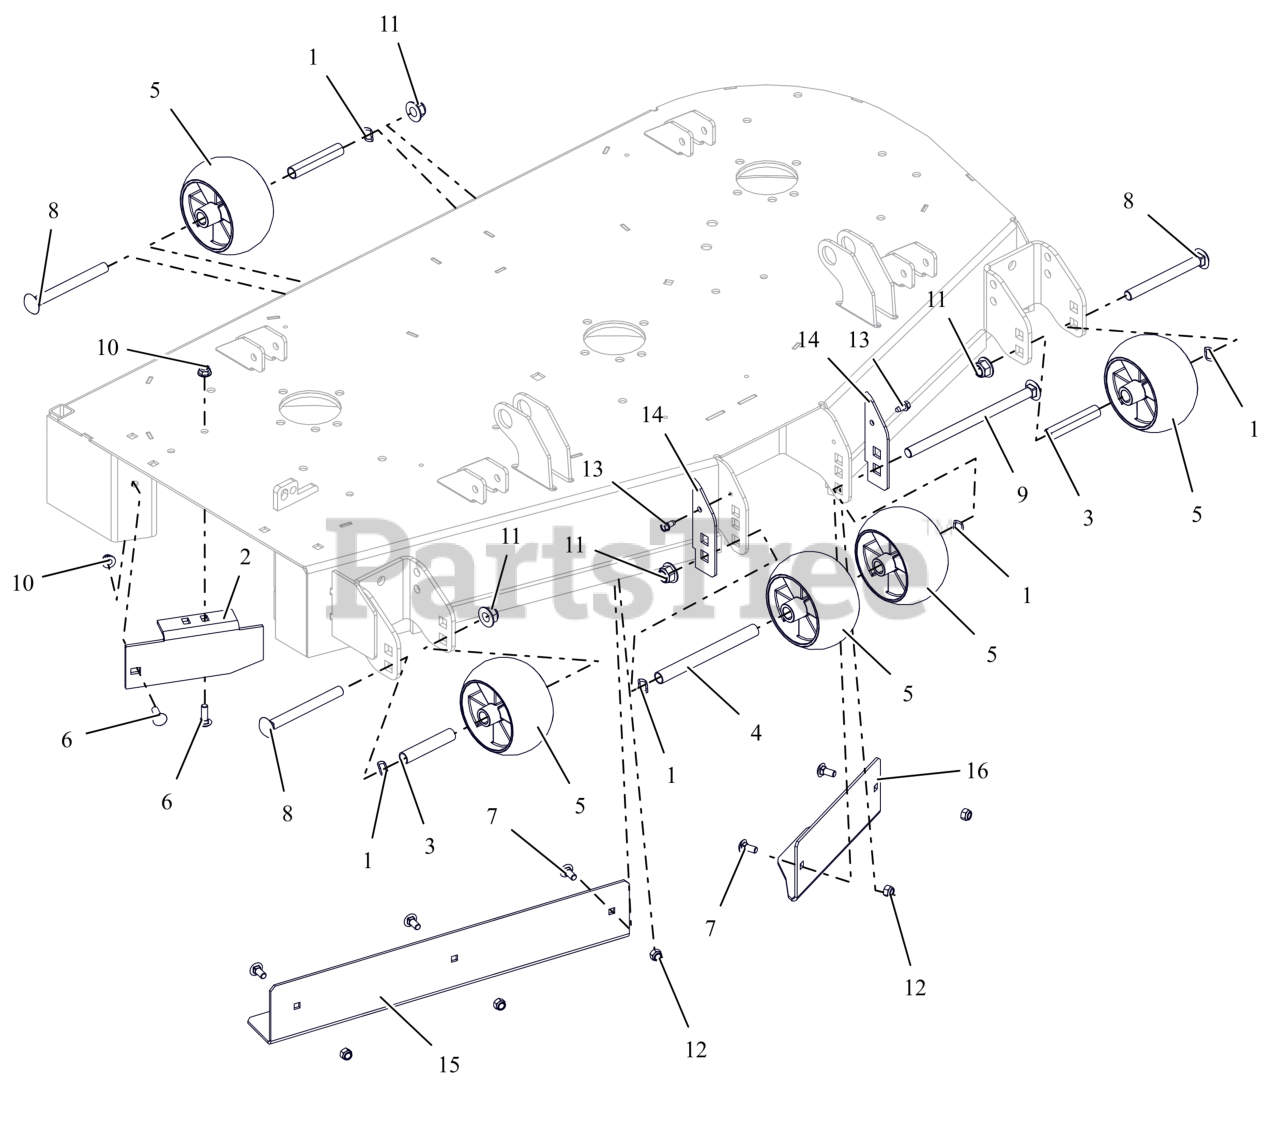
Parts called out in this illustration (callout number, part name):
1	WAVE WASHER .531X.781X.125FH
2	BAFFLE, 44/48" SIDE DISCHARGE
3	SPACER, .510X.625X3.35
4	SPACER, .510X.625X6.50
5	ANTI-SCALP WHEEL - 5X3 CTR
6	BLT,RHSN .31-18X1.00 G5 ZCC
7	BLT,RHSN .31-18X.75 G5 ZCC
8	BLT, RHSN .50-13X5.00 G5 ZCC
9	BLT, RHSN .50-13X8.50 G5 ZCC
10	NUT,LK-NYL-FLG .31-18 G5ZC120
11	NUT,NYL-FLG .50-13 GF ZCC
12	NUT,NYL .31-18 G5 ZCC
13	SCR-TAP .25-20X.50 HWH ZCC
14	PLATE, ANTI SCALP WHEEL PLATE CE (ORANGE)
15	BAFFLE, 48" RH VACUUM (ORANGE)
16	BAFFLE, 44/48" LH VACUUM (ORANGE)
